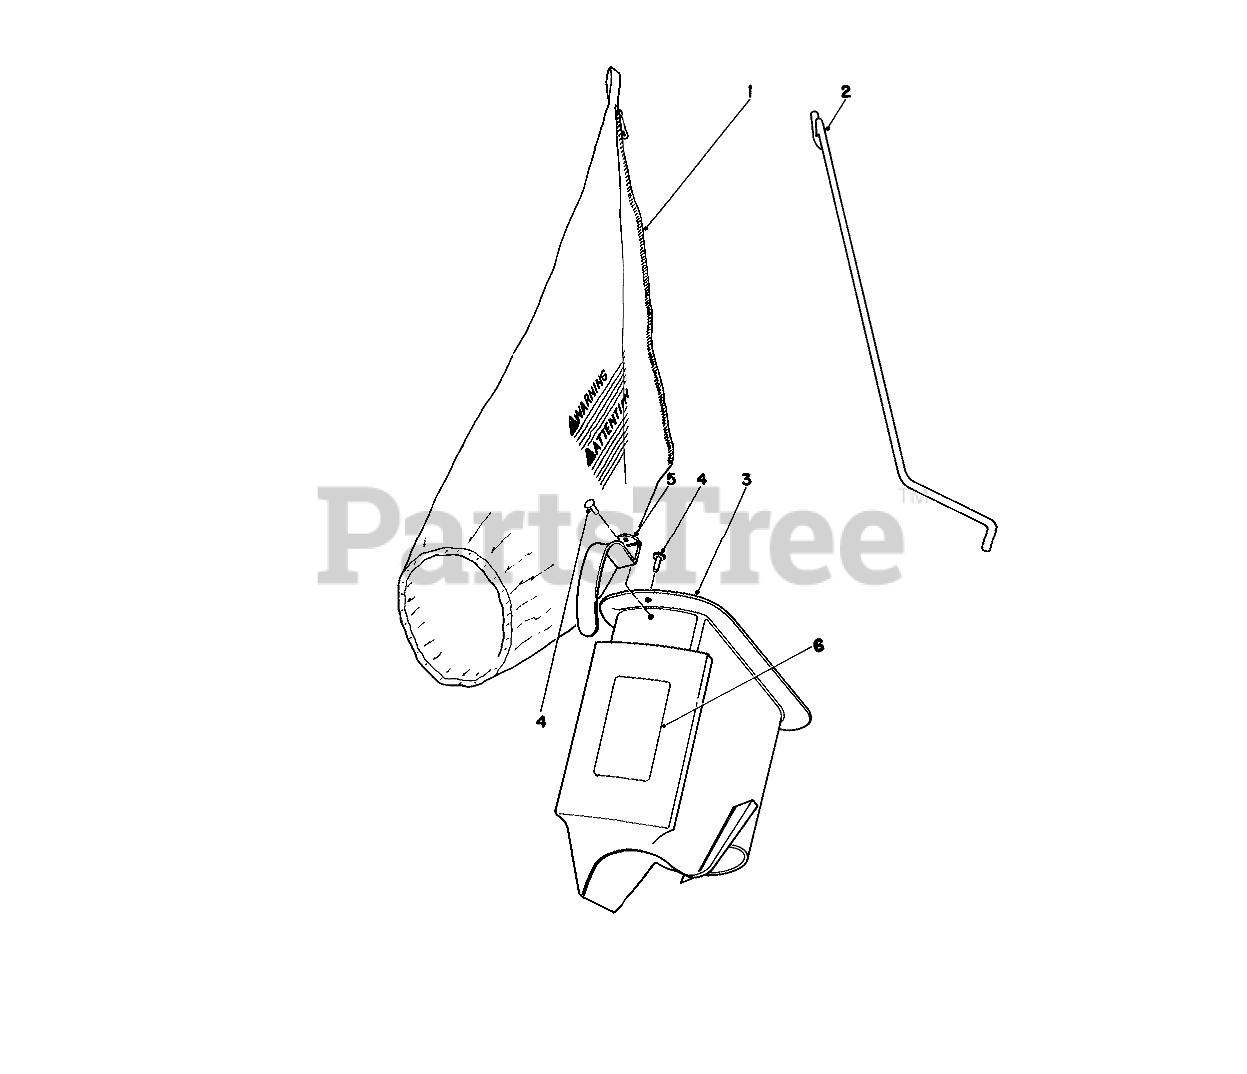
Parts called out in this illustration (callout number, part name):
1	BAG REPLACMNT44-0540
2	Bag Rod
3	Grass Chute (Incl. Ref. #4 & 5)
4	RIVET 3/16 X 7/16
5	HANDLE-GRASS CHUTE
6	BAG CHUTE DECAL
